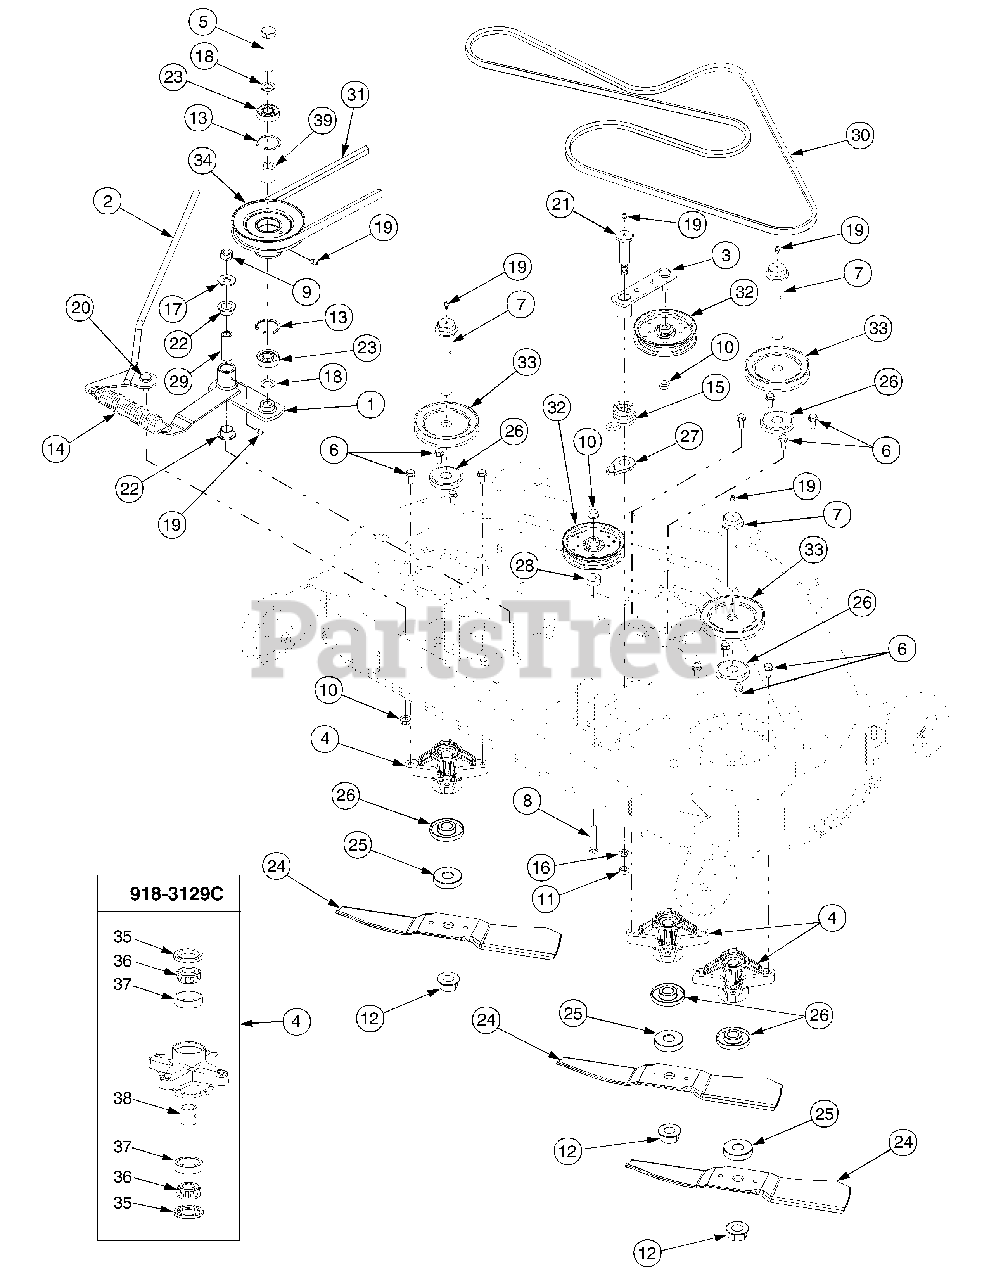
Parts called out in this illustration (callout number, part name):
1	Idler Assembly
3	Idler Arm Assembly
4	Spindle Assembly — Includes Ref. Nos. 35, 36, 37 and 38
5	Screw, Hex Cap, 5/8-18 x 3.0
6	Screw, Hex Wash Ld, 5/16-18 x .75
7	Bolt, Spindle, 3/4-16 x 5.37
8	Screw, Hex Cap, 3/8-16 x 2.0 GR5
9	Nut, Hex Lock, 1/2-20
10	Nut, Flange Lock, 3/8-16
11	Nut, Hex, 7/16-14, GR2
12	Nut, Hex Flange, 3/4-16
13	Snap Ring, Internal
14	Spring, Ext, .162 Dia x 1.25 OD
15	Torsion Spring, Idler, 1.10 ID x 1.3
16	Washer, Lock, 7/16
17	Washer, Flat, 1/2 x 1.25 x .10
18	Washer, Flat, .65 x 1.25 x .075
19	Fitting, Lube, 3/16 Drive
20	Bolt, Shoulder, .498 Dia x .340
21	Screw, Shldr, .68 x 2.11, 7/16-14
22	Bearing, Flange, 3/4 ID x .52 LG
23	Bearing, Ball
24	Blade, Mower, 15.94
25	Spacer, Blade
26	Spacer, Deck Spindle
27	Retainer, Spring
28	Spacer, .406 ID x 1.00 OD x .38
29	Spacer, .5 OD x .75 x 2.07 Lg
30	V-Belt, 1/2 x 103.0 Lg
31	V-Belt, B sect x 111.2 Lg
32	Pulley, Flat w/Flanges
33	Pulley, V-Type, 4.0 Dia
34	Pulley, Double Lube Fitting NOT included.
34	Fitting, Lube, 3/16 Drive
35	Seal, Oil, 1.25 x 1.874 x .25
36	Bearing, Cone
37	Cup, Bearing
38	Spacer, Bearing
39	Spacer, .88 x .635 x 1.25
